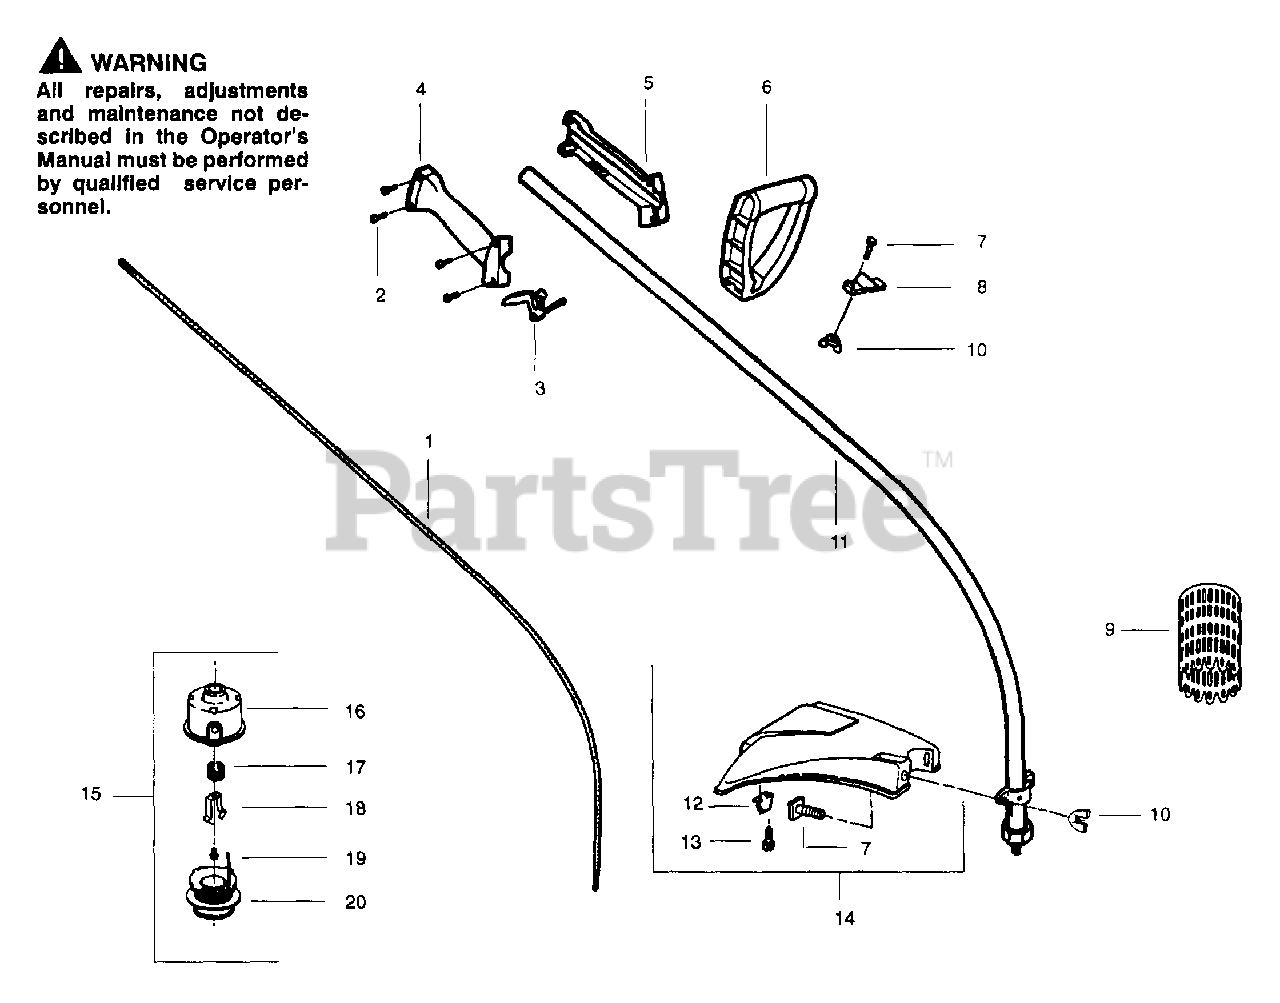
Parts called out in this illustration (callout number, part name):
1	Drive Shaft
2	Screw - Throttle Hsg
4	Throttle Hsg. (Right)
5	Throttle Hsg. (Left)
6	Assist Handle
7	Bolt - Handle/Shield
8	Clamp - Handle
9	Easywrap Treeguard
10	Wingnut - Handle/Shield
11	Drive Shaft Hsg Ass'y
12	Line Limiter
13	Screw - Line Limiter
14	Shield Kit Ass'y
15	Cutting Head Ass'y
16	Hub Ass'y
18	Clip - Retainer - Head
19	Screw w/Washer - Head
20	Spool w/Line
